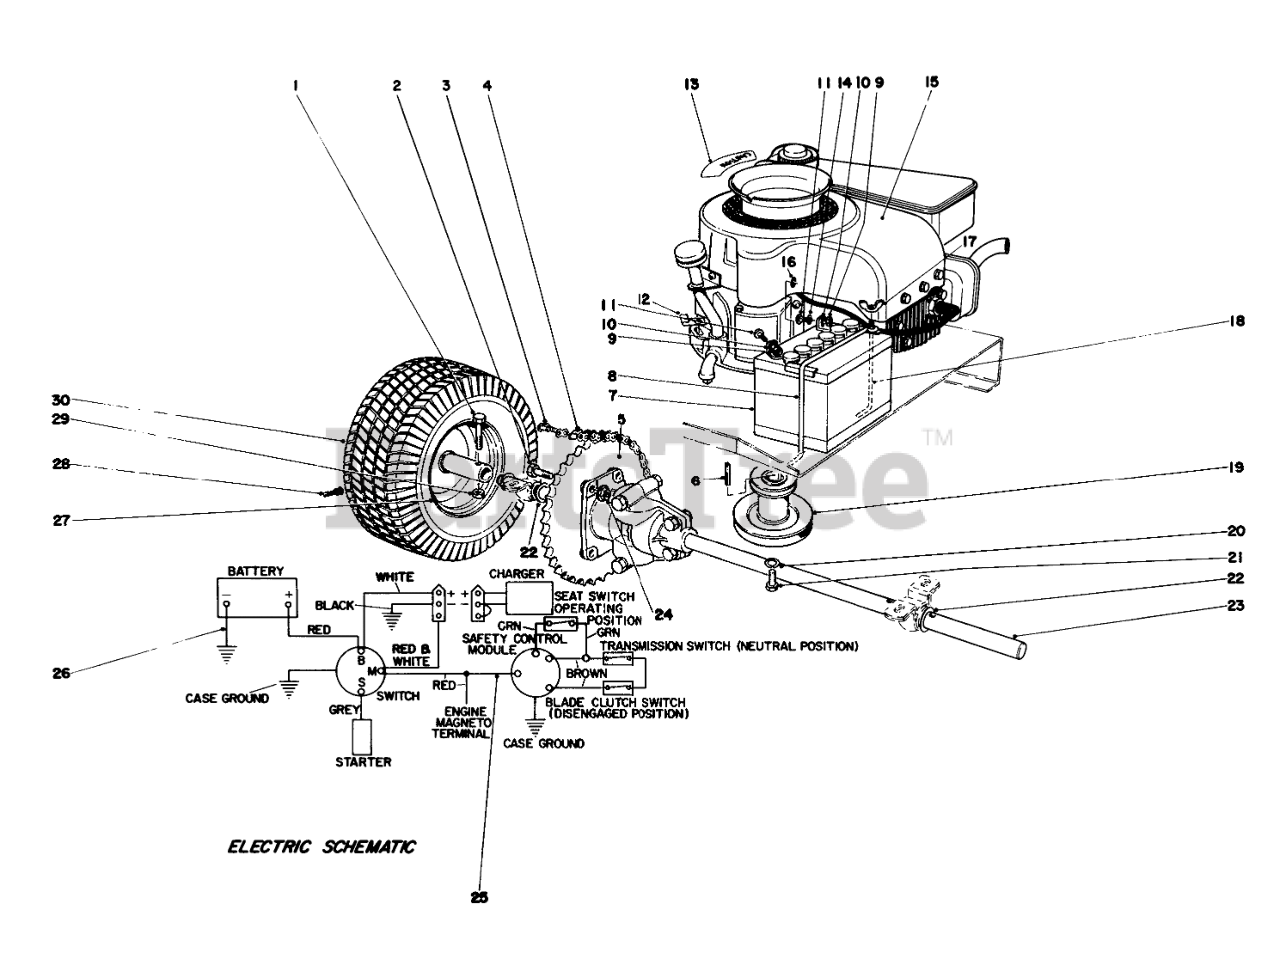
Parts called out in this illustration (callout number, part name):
1	SCREW-HH
2	SCREW-HH
3	LINK-CONNECTING
4	Chain Roller (Incl. Ref. #3)
5	Sprocket
7	BATTERY
8	Battery Clamp
9	NUT-HEX
10	WASHER-LOCK
11	SCREW-HH
13	Decal
14	WASHER-FLAT
15	Engine
16	WASHER-LOCK/EXT
17	NUT-WING SPECL
18	ROD-SUPPORT, BATTERY
19	Engine Pulley
20	WASHER-LOCK
21	SCREW-HH
22	WASHER
23	Differential
24	NUT-LOCK, CONE
25	Wiring Harness
26	ENG-GROUND WIRE ASM
28	STEM-VALVE
29	NUT-LOCK, CONE
30	Tire
